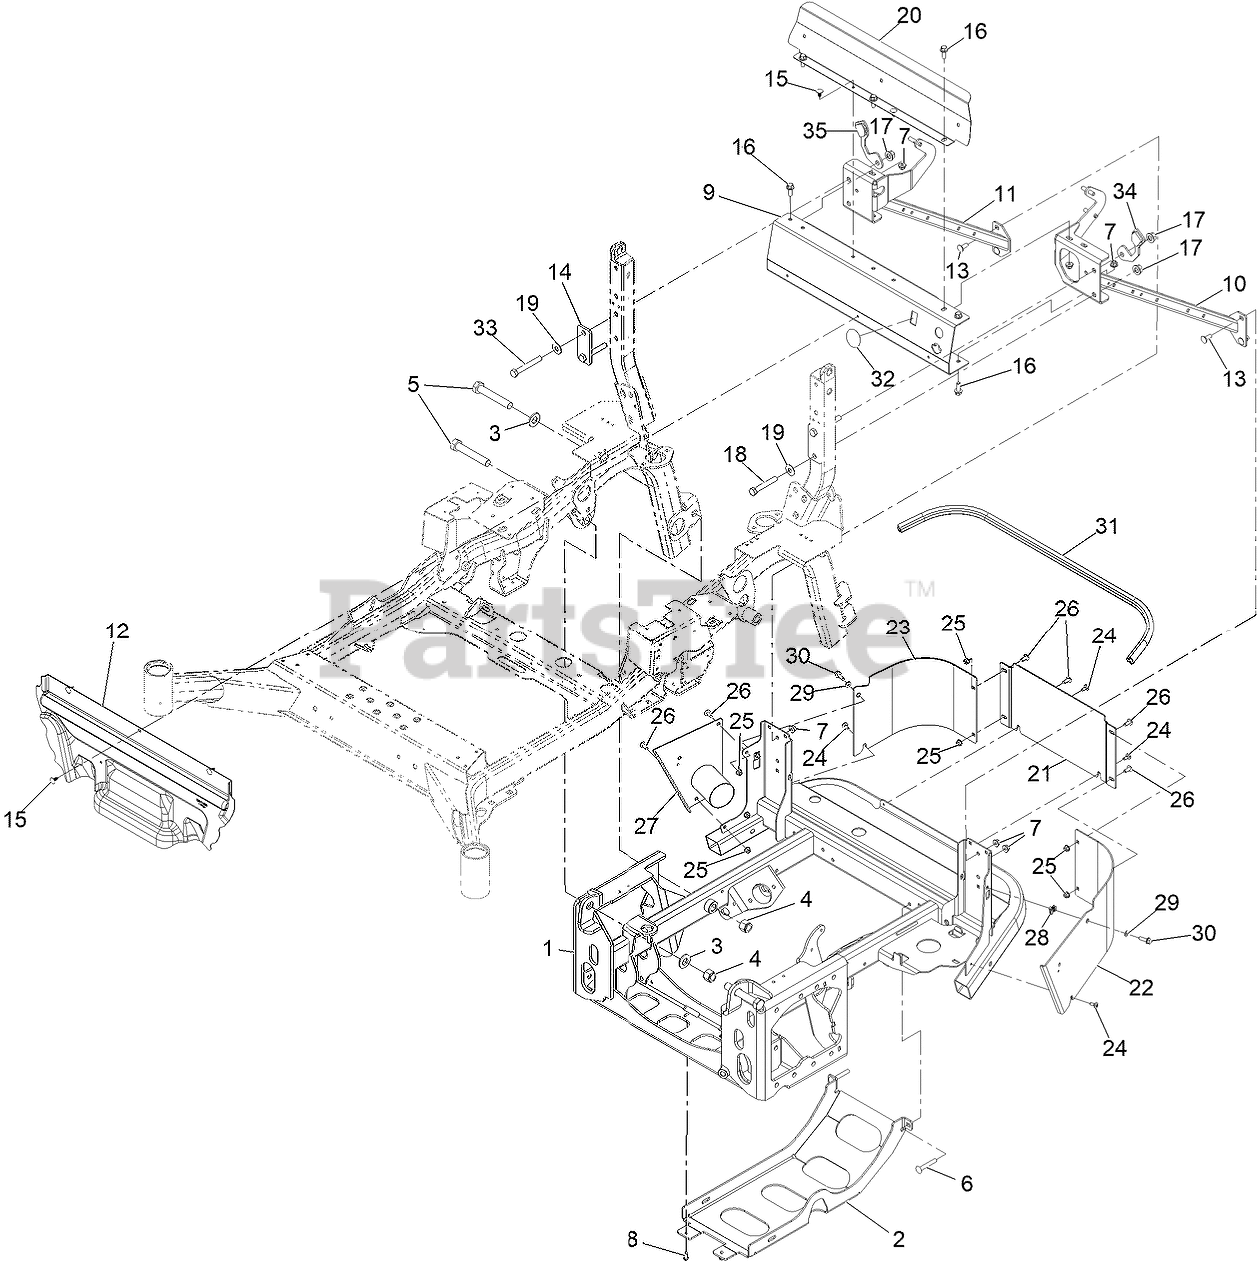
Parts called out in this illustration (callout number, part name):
1	FRAME-POWER
2	PLATE-SKID
4	NUT-LOCK, NI
5	SCREW-HH
6	SCREW-CARR
7	NUT-HF, NI
8	SCREW-BHTF
9	CHANNEL-CROSS
10	BRACE-ROPS, LH
11	BRACE-ROPS, RH
12	PANEL-DEFLECTOR, HEAT
13	SCREW-CARR
14	PLATE-SPACER
15	PLUG-PLASTIC
16	SCREW-HHF
17	Nut-Lock 1/2-13
18	SCREW-HH
19	WASHER-SPRING
20	SHIELD-AIR
21	PLATE-BUMPER, CENTER
22	PLATE-BUMPER, LH
23	PLATE-BUMPER, RH
24	SCREW-SHOULDER
25	NUT-HF, NI
26	SCREW-TORX
27	PLATE-EXHAUST
29	WASHER-BELLEVILLE
30	SCREW-HHF
31	SEAL-BULB
32	DECAL-COVER
33	SCREW-HH
34	STOP-ROPS
35	STOP-ROPS
